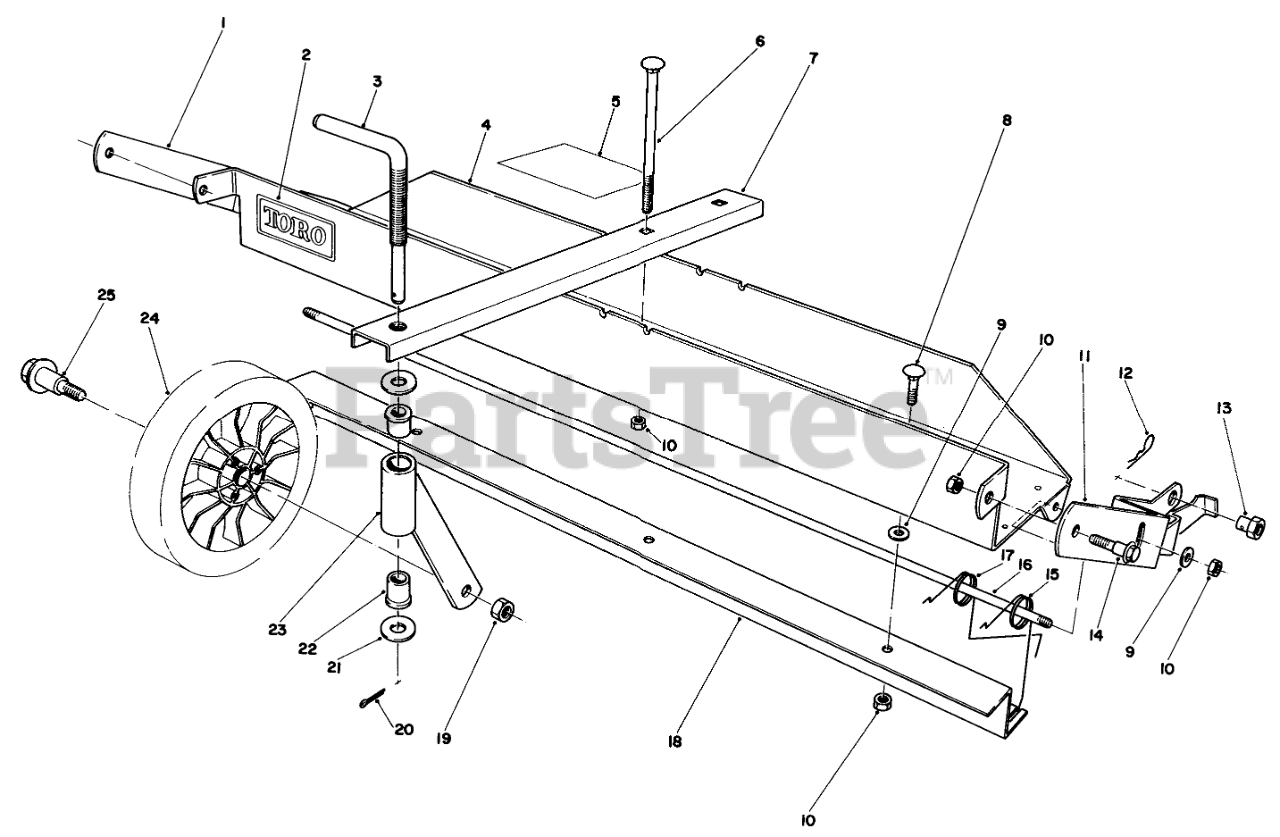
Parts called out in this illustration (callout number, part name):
1	Frame R.H.
2	Decal-Toro
3	CASTOR ADJ ROD
4	Frame-Main (Incl. Ref. #2)
5	Decal-Instruction
6	SCREW-CARR
7	Castor Frame
8	BOLT-CARR
9	WASHER-FLAT
10	NUT-HEX, SIDE DEFORM
11	LH MTG FRAME
12	PIN-COTTER, HAIR
13	PIVOT NUT
14	SCREW-SHOULDER
15	DETHATCHER SPRING
16	SPRING SUPPORT ROD
17	DETHATCHER SPRING
18	SPRING GUIDE STRAP
19	Nut
20	PIN-COTTER
21	WASHER-FLAT
22	FLANGE BUSHING
23	Castor Tube & Support
24	Wheel Assembly
25	BOLT-WHEEL
